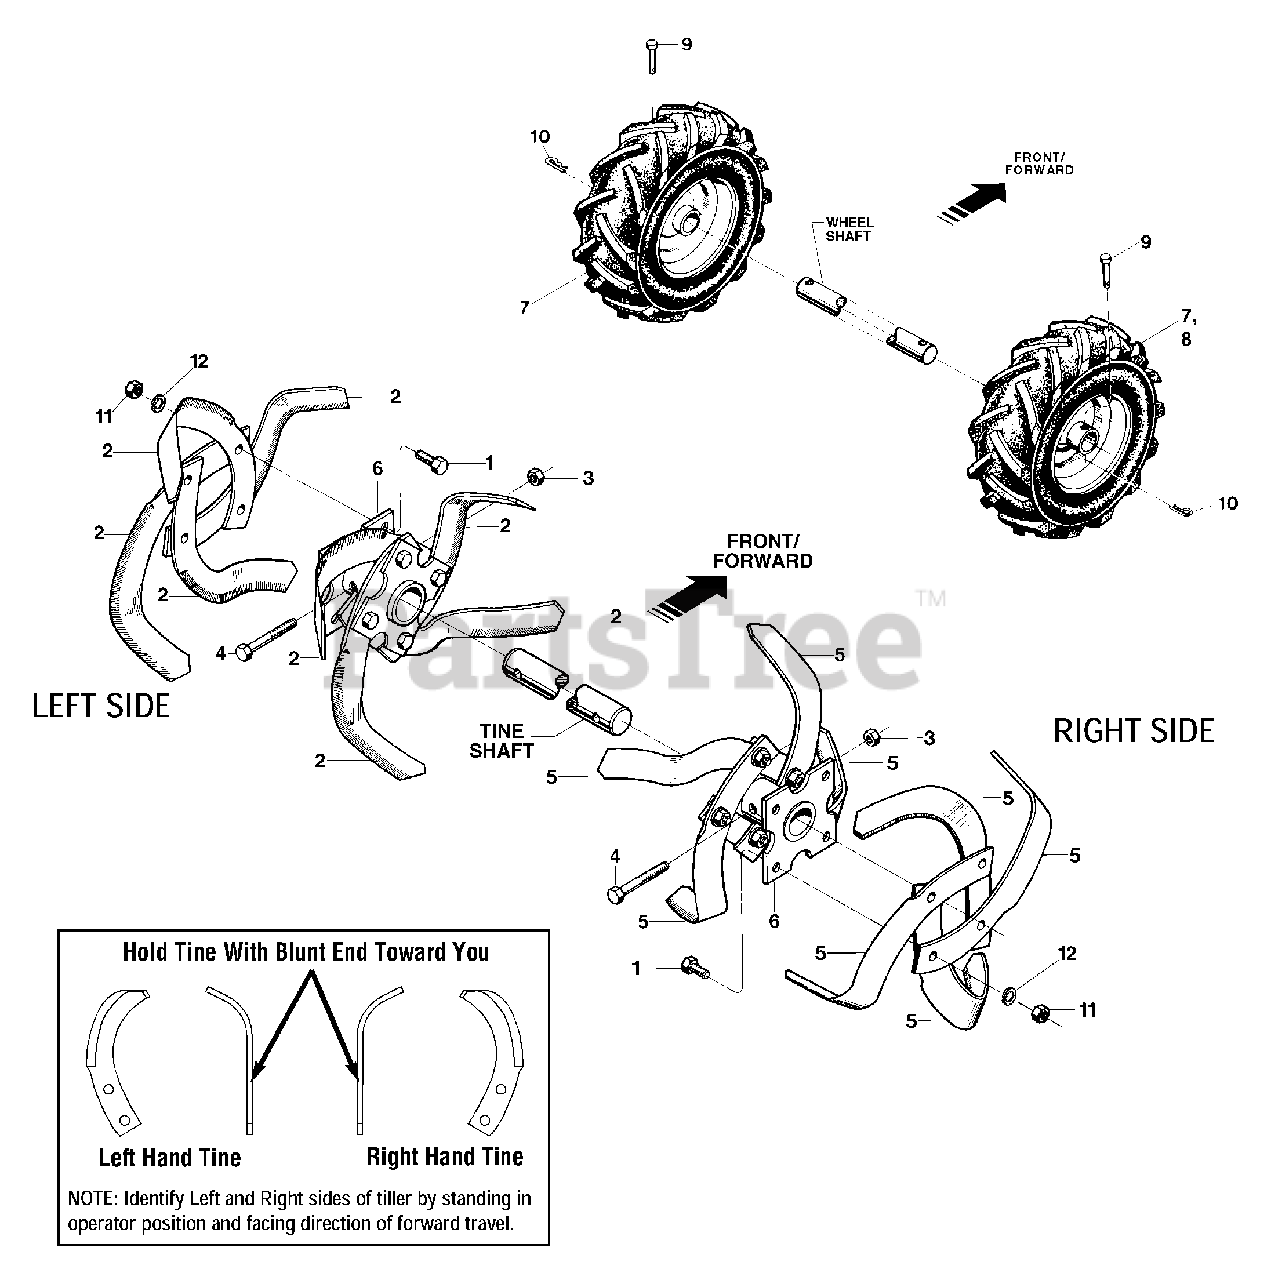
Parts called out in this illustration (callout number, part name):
1	Hex Hd. Screw, 3/8-16 x 1-1/4, Grade 5
2	Bolo Tine - Right Hand.
3	Hex Lock Nut, 3/8-16
4	Hex Hd. Screw, 3/8-16 x 1-3/4
5	Bolo Tine - Left Hand.
6	Tine Holder
7	Wheel & Tire Ass'y.
8	Wheel & Tire Ass'y. - Right Side
9	Clevis Pin, .312" x 1-3/4"
10	Hair Pin Cotter
11	Hex Nut, 3/8-16
12	Lock Washer, 3/8
